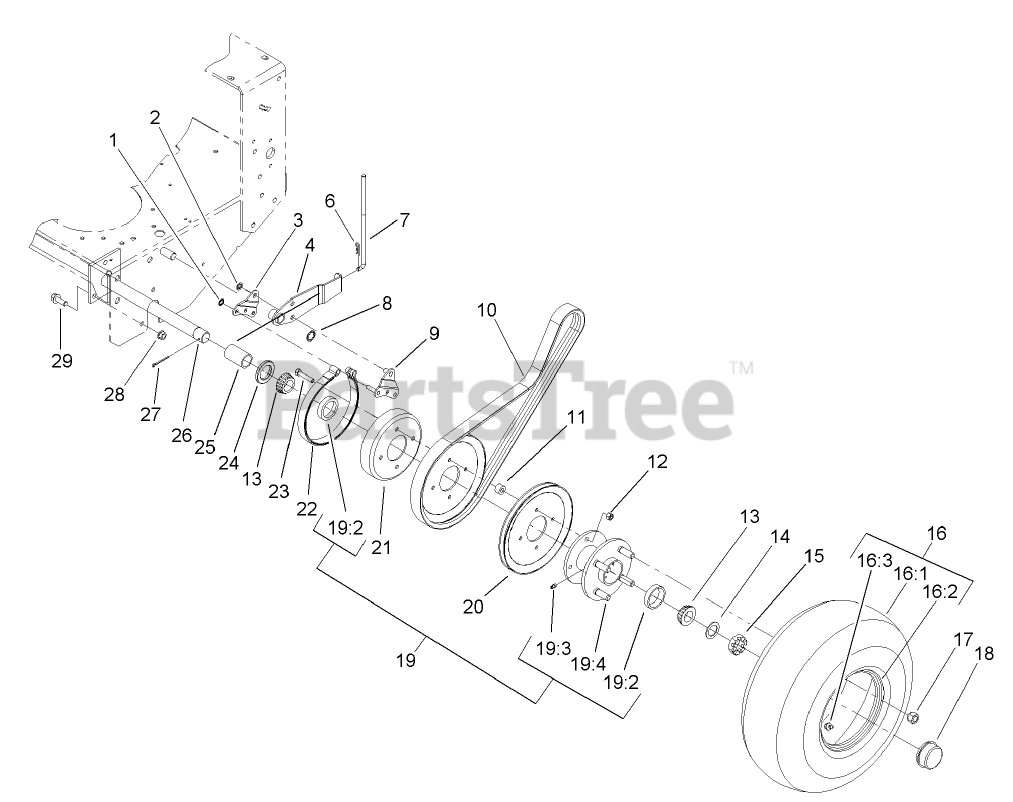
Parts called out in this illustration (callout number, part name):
1	RING-RETAINING
2	RING-RETAINING, EXTERNAL
3	PLATE-LINK, BRAKE
4	BRAKE ARM ASM
6	PIN-COTTER
7	ROD-BRAKE
8	RING-RETAINING
9	BRAKE LINK ASM
10	V-BELT
11	SPACER-PULLEY
12	NUT-LOCK, NI
13	BEARING-CONE, TAPERED
14	WASHER-SPACER
15	NUT-SHH
16	WHEEL AND TIRE ASM
16:2	WHEEL
16:3	STEM-VALVE
17	NUT-LUG
18	CAP-DUST
19	HUB/WHEEL ASM
19:2	BEARING-CUP, TAPERED
19:3	FITTING-GREASE
19:4	STUD-WHEEL
20	PULLEY-WHEEL
21	DRUM-BRAKE
22	BAND-BRAKE
23	SCREW-HH
24	SEAL-GREASE
25	SPACER-WHEEL
26	AXLE ASM
27	PIN-COTTER
28	NUT-HF
29	SCREW-HHF
